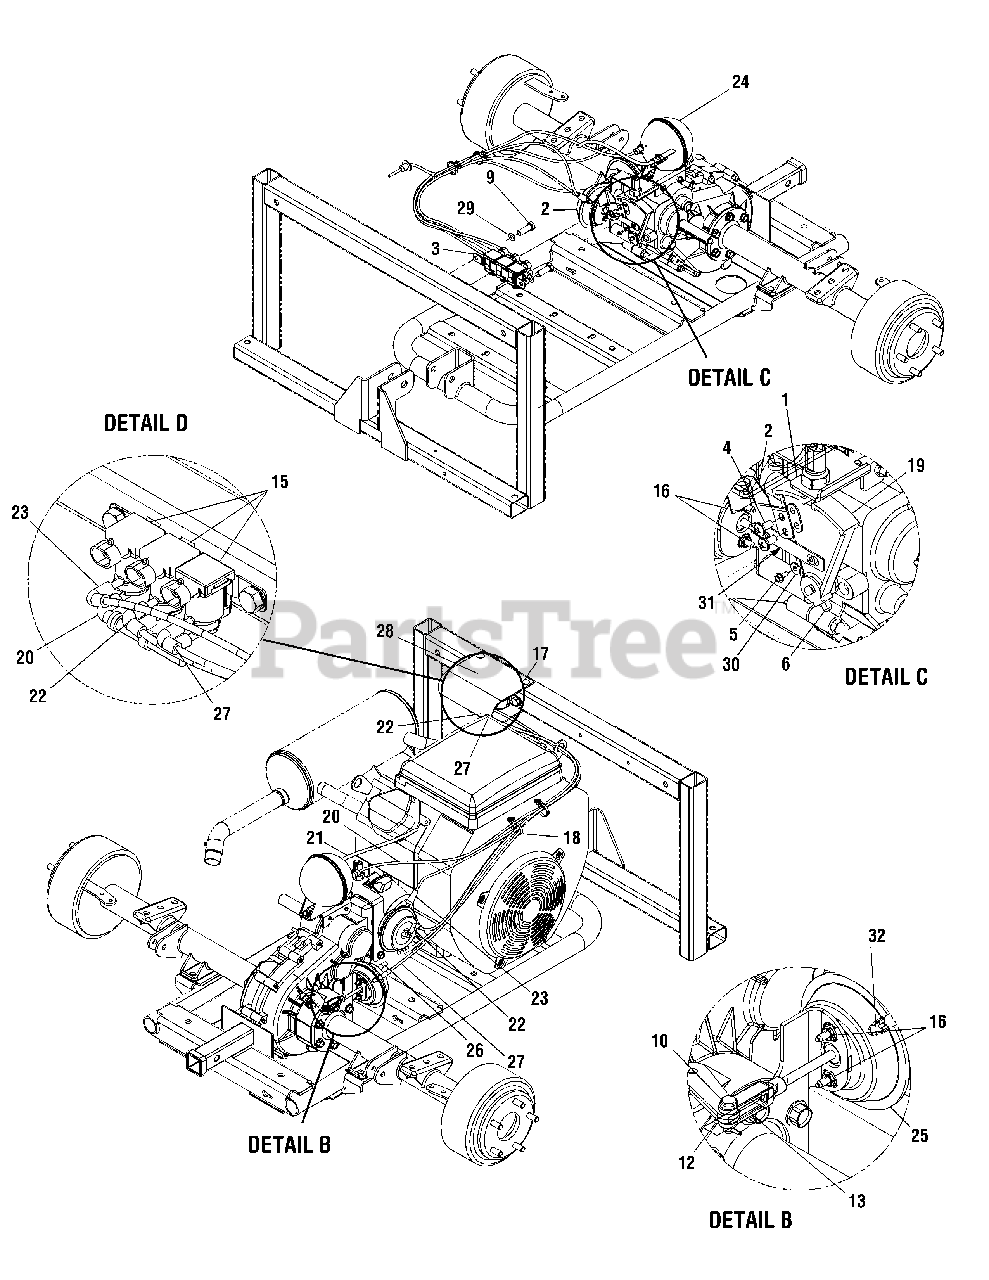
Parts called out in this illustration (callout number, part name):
1	Mounting Bracket, Vacuum Actuator
2	Bracket, Shift
3	Bracket, Vac Relay
4	Screw, 1/4-20 x.5
5	Screw, Hex. #8 - 18 .375
6	Screw, Set, 5/16-24 x .50 LG
7	Screw, 5/16-18
8	Screw, 1/4-14
9	Screw, 5/16-18 x .75 Hex
10	Pin, Yoke 1/4
11	Nut, Hex 9/16-18
12	Pin, Cotter 1/16x.750
13	Yoke, 1/4-28
14	Switch, Neutral
15	Solenoid, Kit Vacuum Actuator
16	Self Threading Nut
17	Clip, Panel Retainer
18	Cable Tie
19	Arm, Shift
20	Hose, Kohler
21	Hose, Manifold Vacuum
22	Hose, Actuator Vacuum
23	Hose, Actuator Vacuum
24	Reservoir, Air
25	Actuator, Vac Differential Lock
26	Differential Lock Vent 3/8 dia.
27	Hose, Vac Differential Lock Supply
28	Cover, Solenoid
29	Flat Washer, .330 x .687 x .030
30	Flat, Washer, .188 x .437 x .042
31	Actuator, Vacuum Shift
32	Straight Fitting
